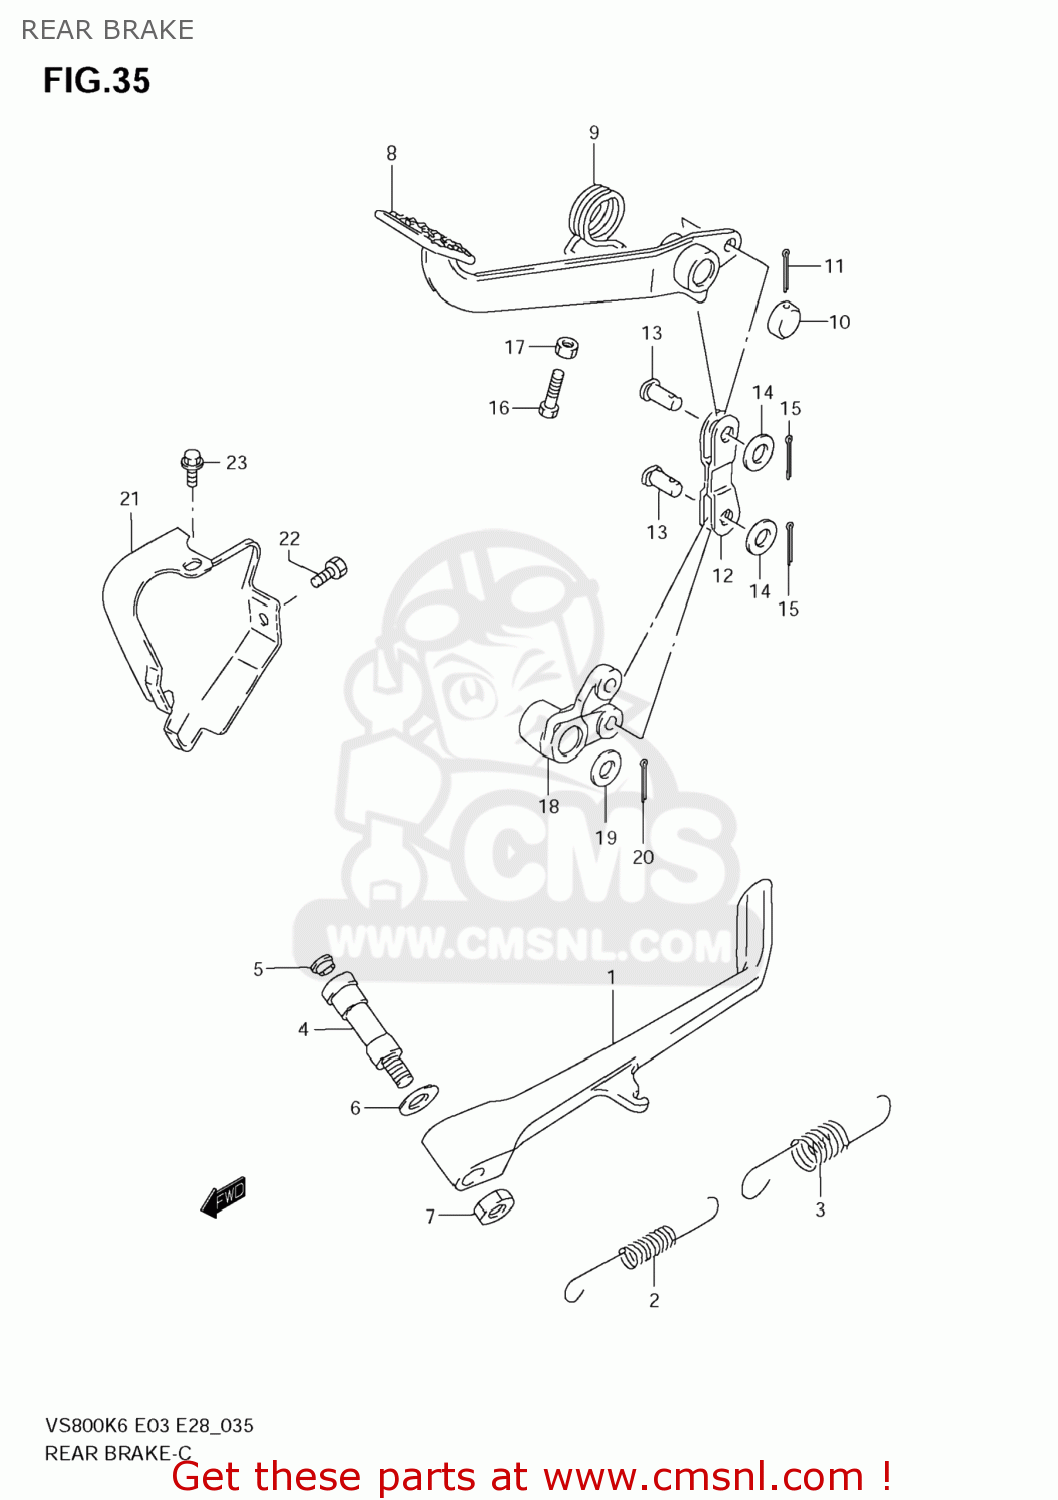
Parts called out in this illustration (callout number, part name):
1	STAND,PROP
2	SPRING
3	SPRING
4	BOLT,PROP STAND
5	CAP
6	SHIM(15X24X0.5)
7	NUT
8	PEDAL ASSY,BRAKE
9	SPRING
10	CAP,BRAKE PEDAL
11	PIN
12	LINK,BRAKE ROD NO.1
13	PIN
14	WASHER
15	PIN
16	BOLT
17	NUT
18	ARM,BRAKE PEDAL LINK
19	WASHER(16.5X22X1)
20	PIN
21	COVER,BRAKE
22	SCREW(6X10)
23	BOLT
